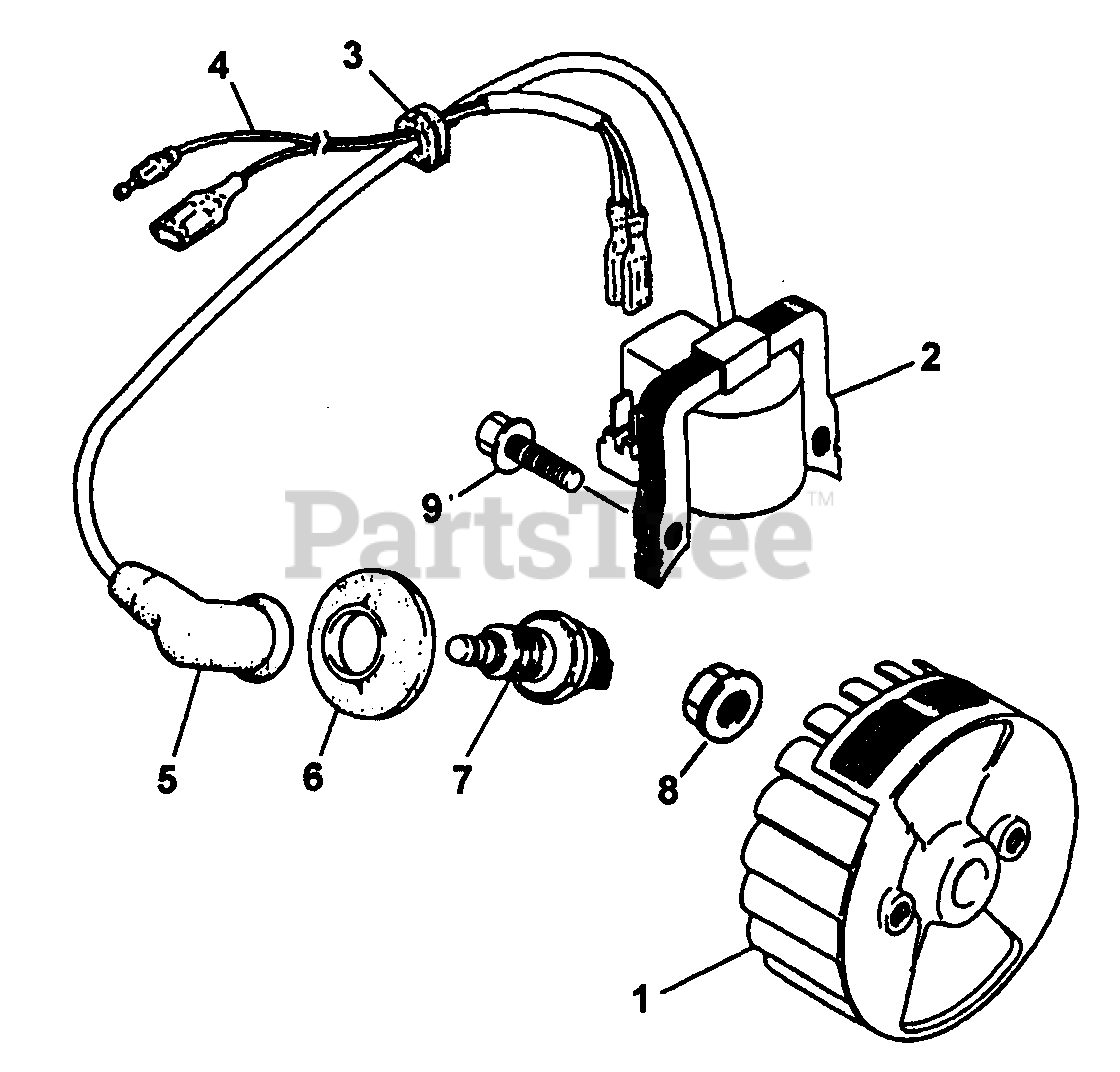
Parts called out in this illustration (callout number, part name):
2	MODULE, IGNITION
3	GROMMET
4	WIRE, LEAD
5	CAP, PLUG
6	CAP, PLUG
7	SPARK PLUG
8	NUT, CONICAL
9	BOLT & WASHER
